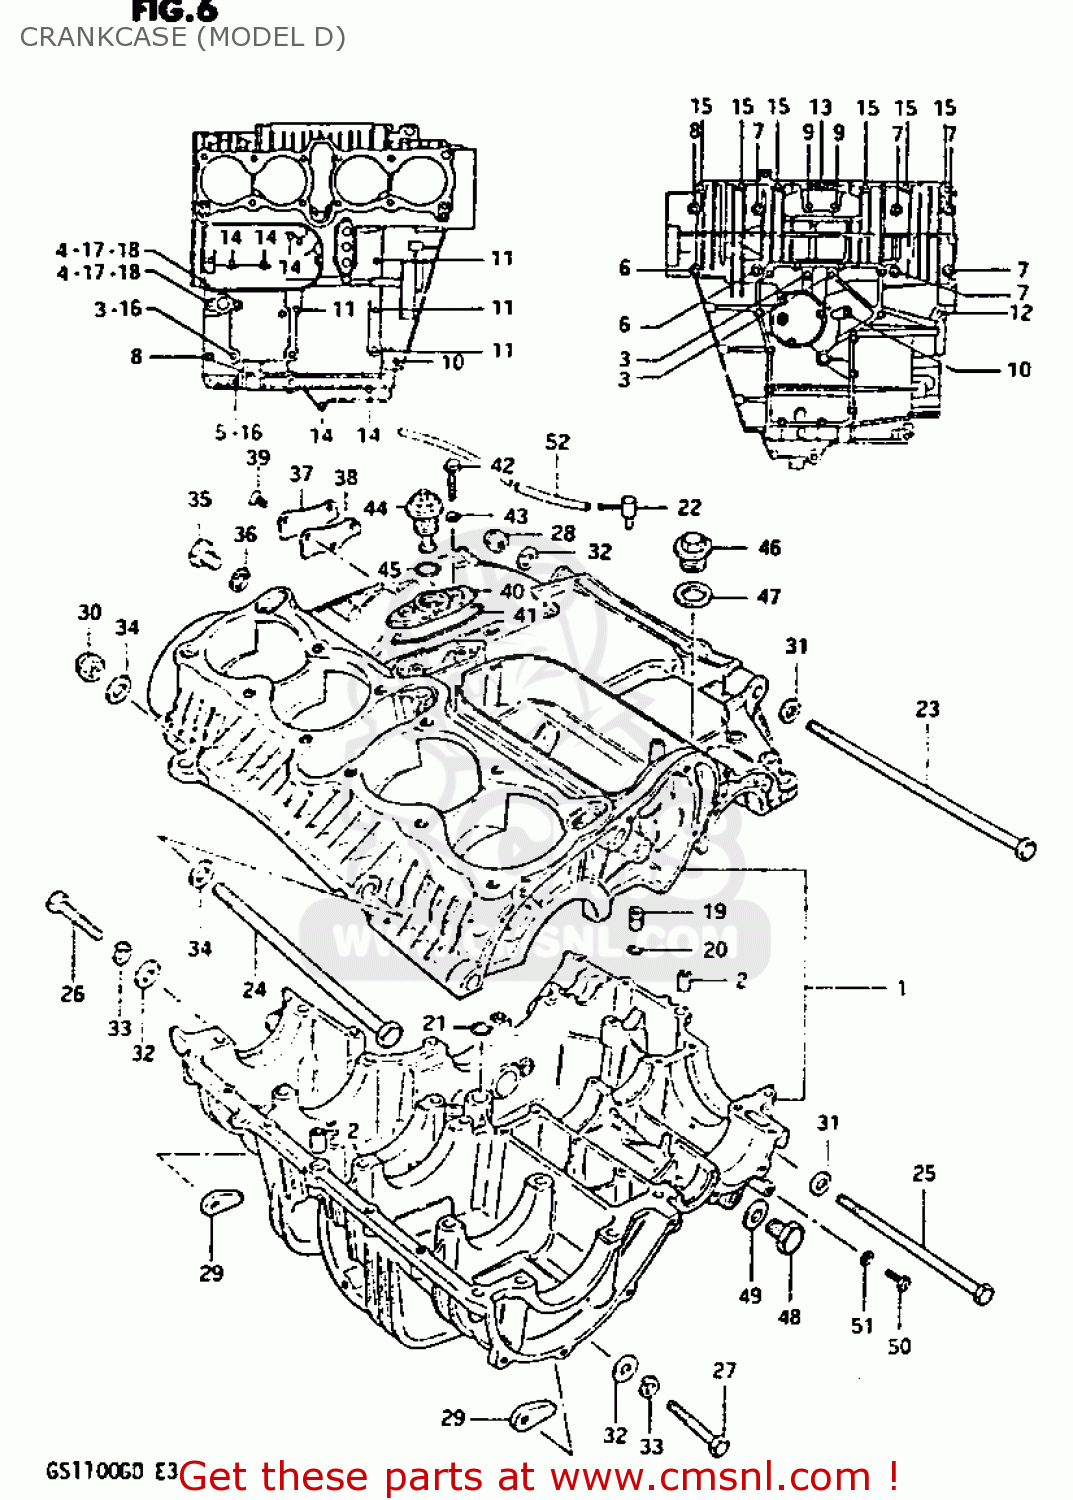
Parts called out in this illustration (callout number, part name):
1	CRANKCASE SET
2	PIN
3	BOLT(8X125)
4	BOLT 8X110
5	BOLT
6	BOLT
7	BOLT (8X90)
8	BOLT (8X65)
9	BOLT 8X60
10	BOLT (6X90)
11	BOLT (6X75)
12	BOLT 6X55
13	BOLT 6X50
14	BOLT (6X45)
15	BOLT 6X35
16	NUT 8MM
17	NUT
18	GASKET 8.2X14X1 (NAS)
19	UNION
20	O RING(D:1.05,ID:3.1)
21	O RING(D:3.2,ID:12.9)
22	BPLUG,BEVEL GEAR BREATHER
23	BOLT
24	SHAFT,REAR SWING ARM
25	BOLT
26	BOLT (10X60)
27	BOLT (10X50)
28	NUT (10MM)
29	NUT
30	NUT
31	WASHER(10.5X20X3.2)
32	WASHER 10MM
33	WASHER,LOCK
34	WASHER
35	PLUG(14X12)
36	GASKET(14X19.2X2) (NAS)
37	CAP,OIL GALLERY
38	GASKET,OIL GALLERY CAP (NAS)
39	SCREW
40	HOUSING,OIL PRESSURE SWITCH
41	O RING,PRESSURE SWITCH HOUSING
42	BOLT
43	GASKET(5.8X13X1.2) (NAS)
44	SWITCH ASSEMBLY
45	O RING(D:1.9,ID:18.8)
46	PLUG
47	GASKET
48	PLUG
49	GASKET(14X19.2X2) (NAS)
50	SCREW(6X10)
51	GASKET(5.8X13X1.2) (NAS)
52	HOSE
